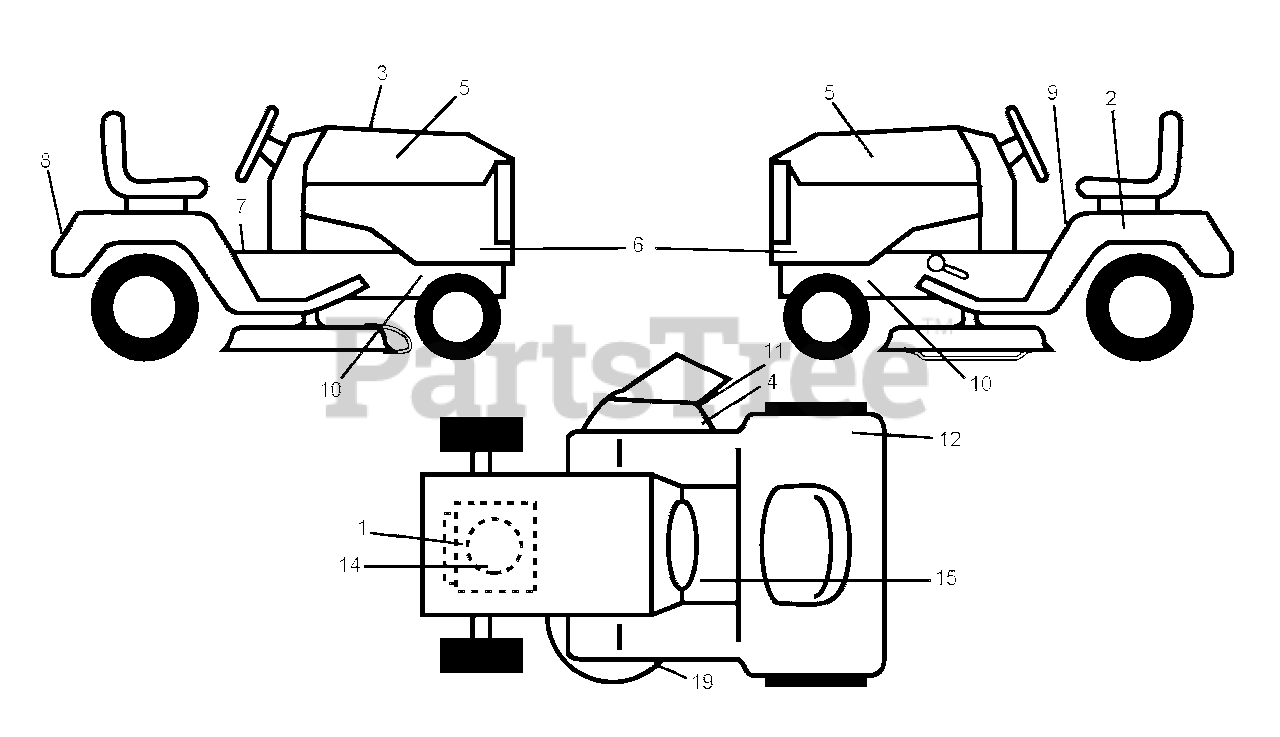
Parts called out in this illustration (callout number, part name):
2	DECAL BTRY SYMBOLS
4	DECAL, DEFLECT WARNING
7	DECAL PARK BRAKE
11	DECAL.INTERNATIONL.CUTFINGER
19	DECAL.V-BELT.SCHEMATIC.36/38/9
